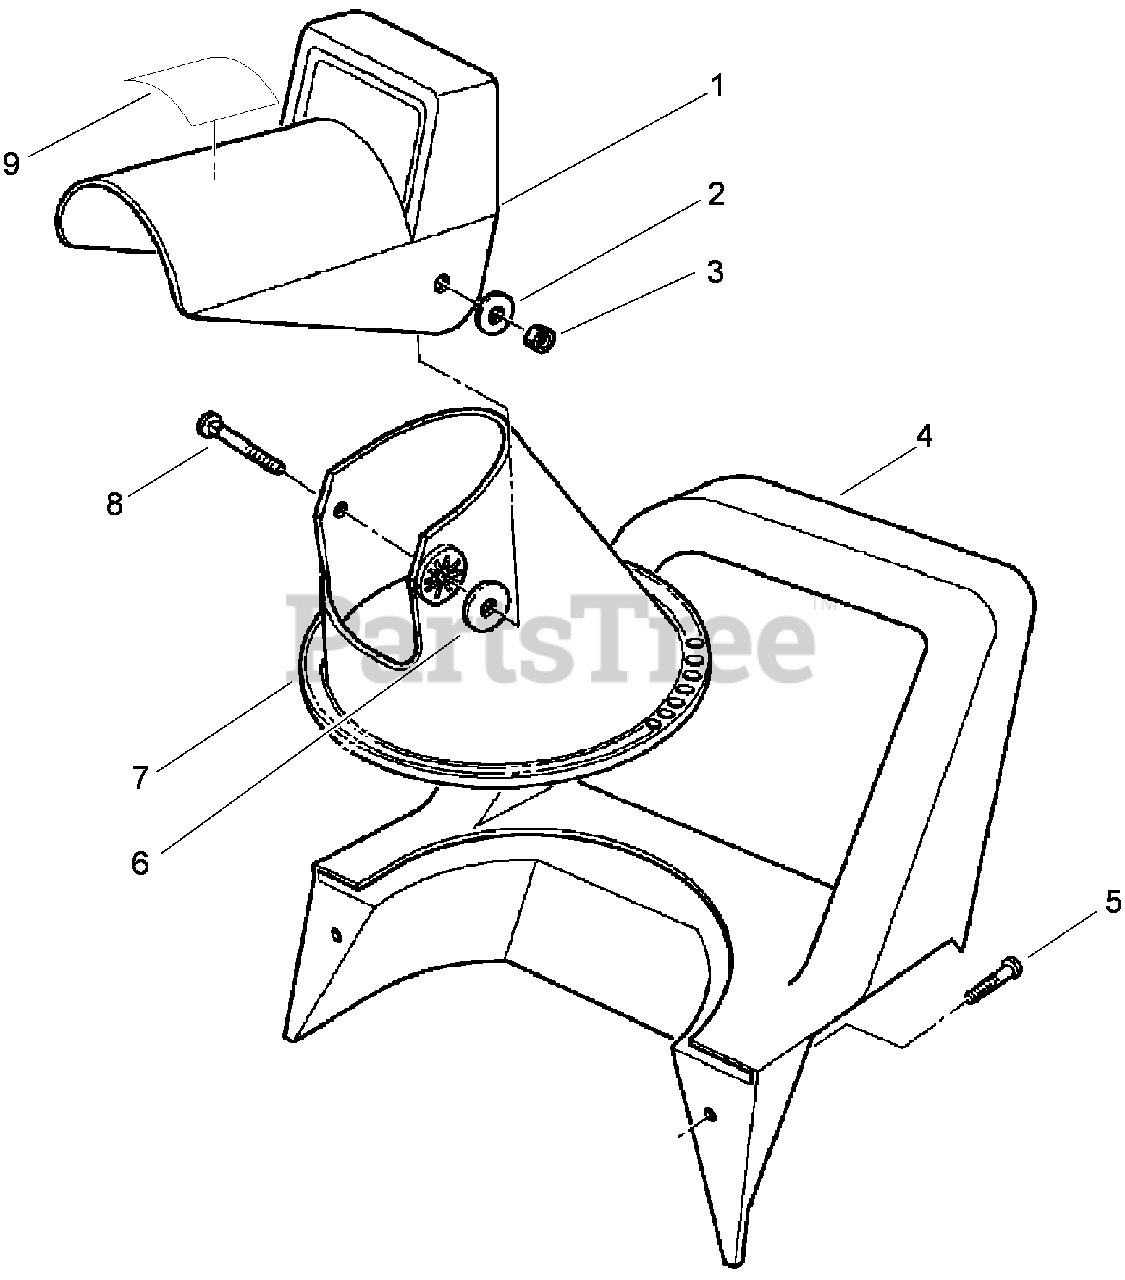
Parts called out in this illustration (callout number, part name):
1	Chute-Deflector
2	WASHER-FLAT
3	NUT-LOCK, NI
4	Handle-Middle
5	SCREW-PPH
6	WASHER-RUBBER
7	Chute-Lower
8	BOLT-CARR
9	Decal-Danger
